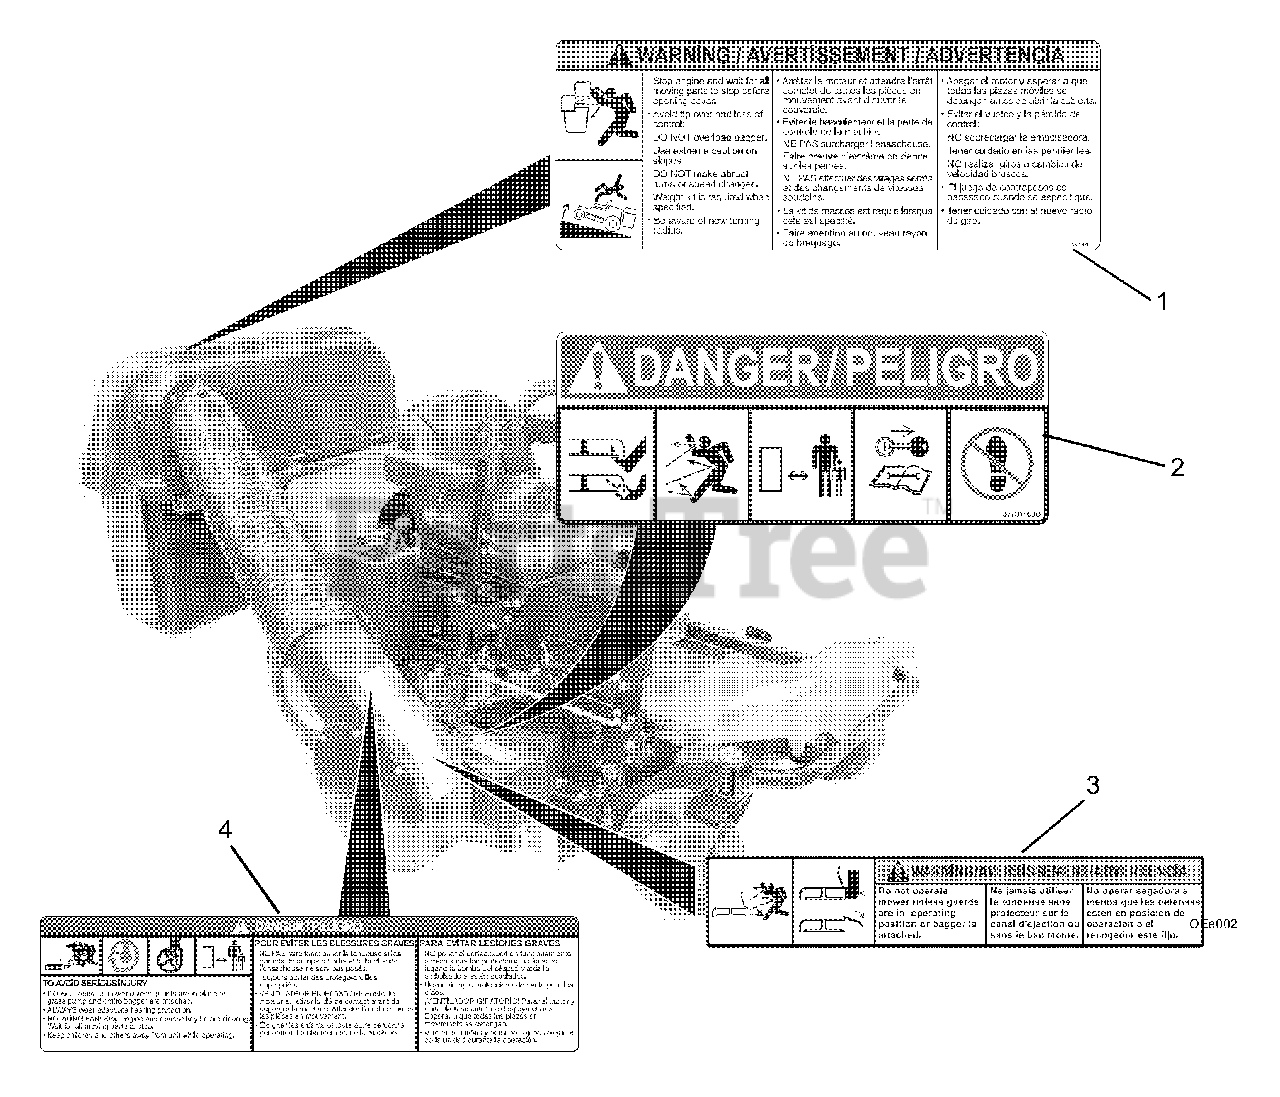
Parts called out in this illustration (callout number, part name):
1	DECAL, BAGGER COVER
2	DECAL, MOWER PAN DANGER
3	DECAL, WARNING
4	DECAL-CAUTION, GRASS PUMP
